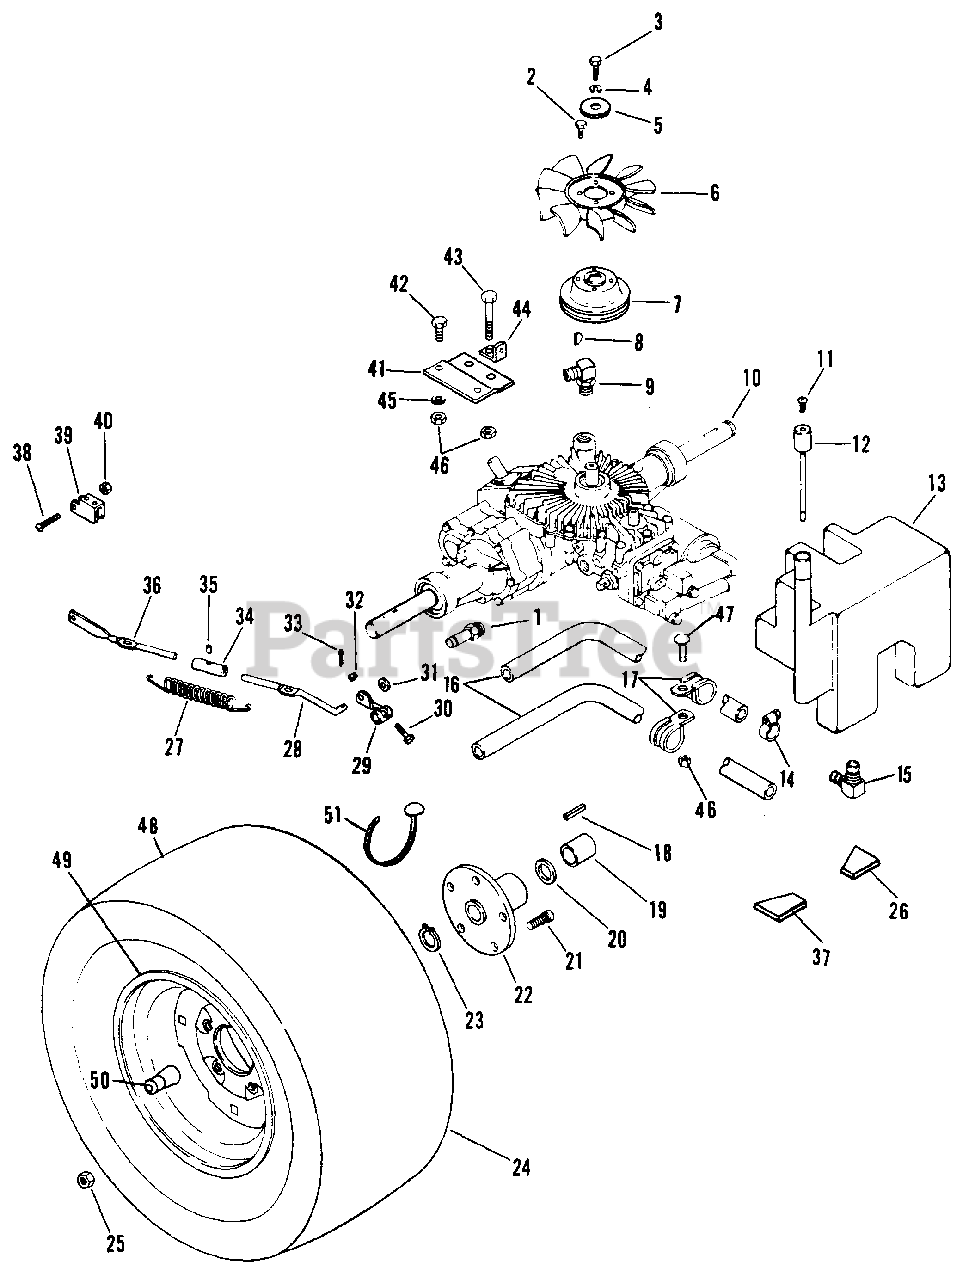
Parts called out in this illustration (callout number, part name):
1	Adapter, #4604-10-10
2	Screw, Mach. 10-24 x .50 PHD
3	Bolt, Hex 1/4-20 x .750
4	Washer, Lock 1/4 Reg.
5	Washer, Special
6	Fan
7	Pulley, Transaxle
8	Key, Woodruff .187 x .625 Hrd. #61
9	Fitting
10	Transaxle
11	Screw, Vent
12	Dipstick
13	Tank, Hydraulic
14	Clamp, .88 DIA. Hose
15	Fitting, O-Ring Barb S/A
16	Hose, Hydraulic
17	Clamp, Steel 1.00
18	Key, Straight
19	Bush., St. 1.44 x 1.01 x 1.92 Stl.
20	Race, Bearing Thrust .095
21	Lug Bolt
22	Hub, Wheel
23	Snap Ring
24	Asm., Wheel 23 x 8.50-12
25	Nut, Lug 7/16-20
26	Pad, Tank L.H.
27	Spring, Extension
28	Front Dump Valve Rod
29	Dump Valve Arm
30	Bolt, Hex 1/4-20 x 1.00
31	Washer, Flat .406 x .812 x .065
32	Nut, Lock 1/4-20
33	Pin, Cotter .094 x .75
34	Collar
35	Pin, Roll .125 x .625
36	Rear Dump Valve Rod
37	Pad, Tank R.H.
38	Screw, Mach. 10-24 x 1.0 PHCR
39	Latch
40	Nut, Lock 10-24
41	Bracket, Transaxle Mounting
42	Bolt, Hex 3/8-16 x .875
43	Bolt, Hex 3/8-16 x 3.25
44	Spring Anchor
45	Washer, Flat .375 x 1.125 x .065
46	Nut, Lock 3/8-16
47	Bolt, 3/8-16 x 1.00 Rd Hd Sq Nk
48	Tire, Rear 23 x 8.50-12
49	Weldment, Rim Rear
50	Assembly, Valve Stem
51	Clamp, Universal
